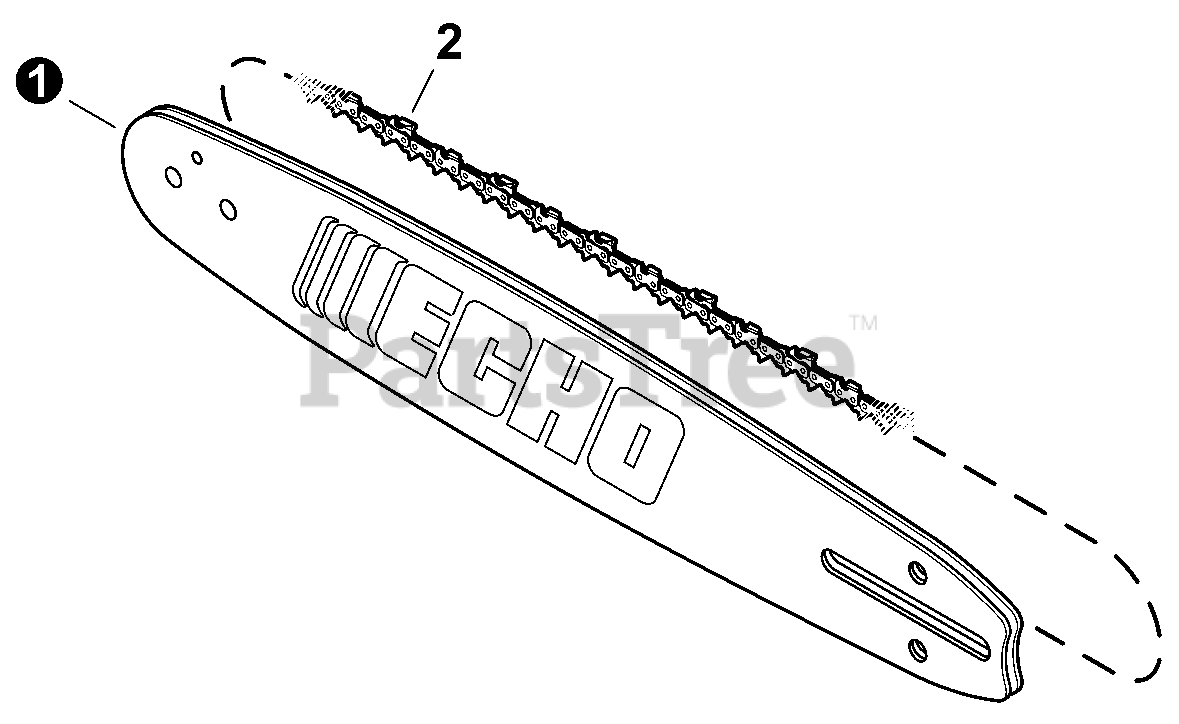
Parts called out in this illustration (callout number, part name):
1A	GUIDE BAR, 20" POWER MATCH
1B	GUIDE BAR, 24" POWER MATCH
1C	GUIDE BAR, 27" POWER MATCH
1D	GUIDE BAR, 32" POWER MATCH
1E	GUIDE BAR, 36" POWER MATCH
2A	SAW CHAIN - 20"
2B	SAW CHAIN - 24"
2C	SAW CHAIN - 27"
2D	SAW CHAIN - 32"
2E	SAW CHAIN - 36"
